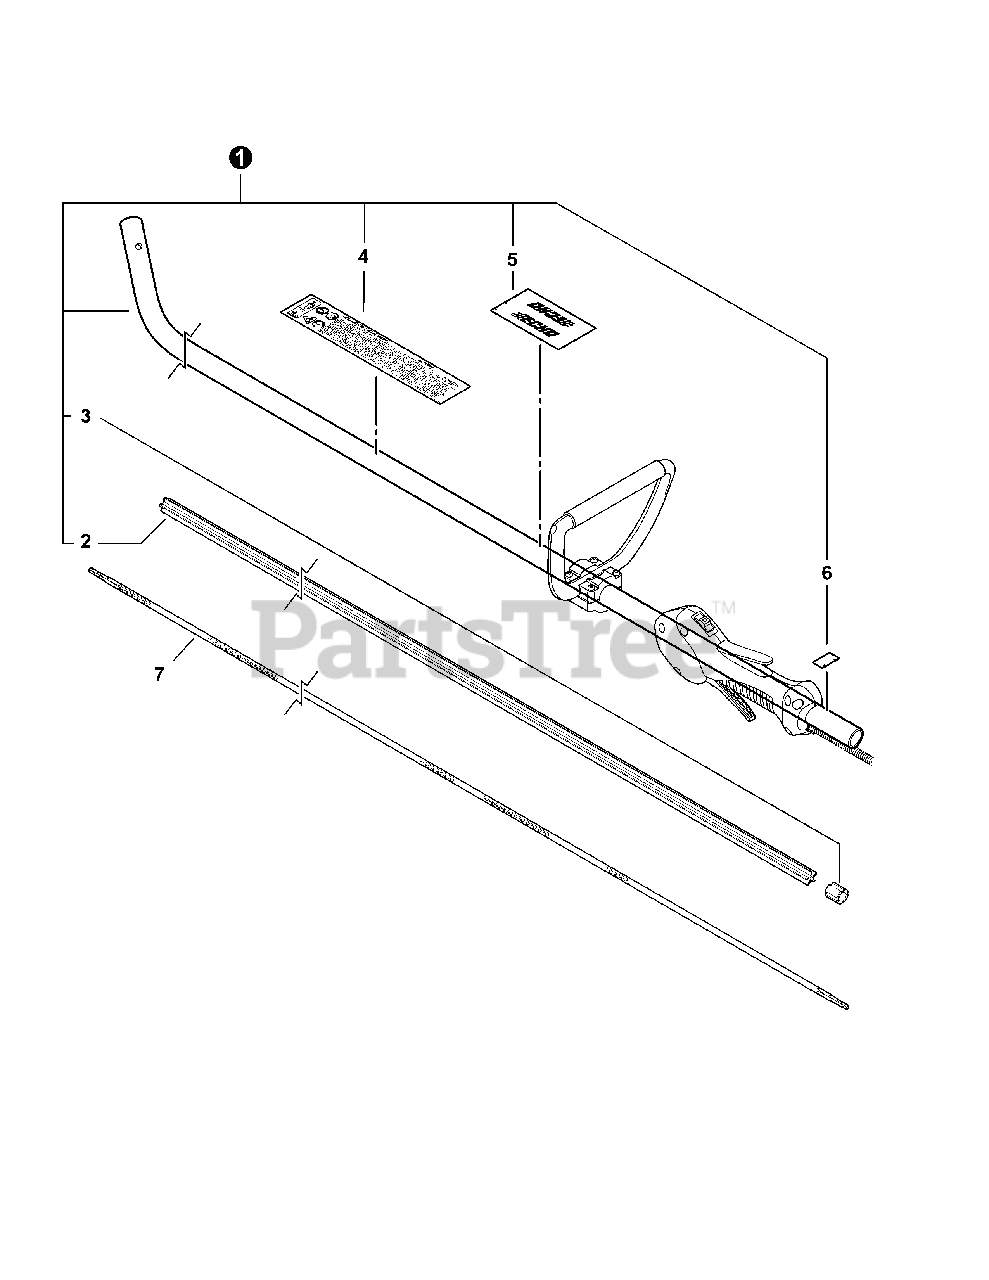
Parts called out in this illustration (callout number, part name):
1	MAIN PIPE ASSY
2	LINER, FLEXIBLE 21.6×1420
4	LABEL, CAUTION
5	LABEL, HANDLE LOCATION
6	LABEL - ALIGNMENT
7	DRIVESHAFT - FLEXIBLE
